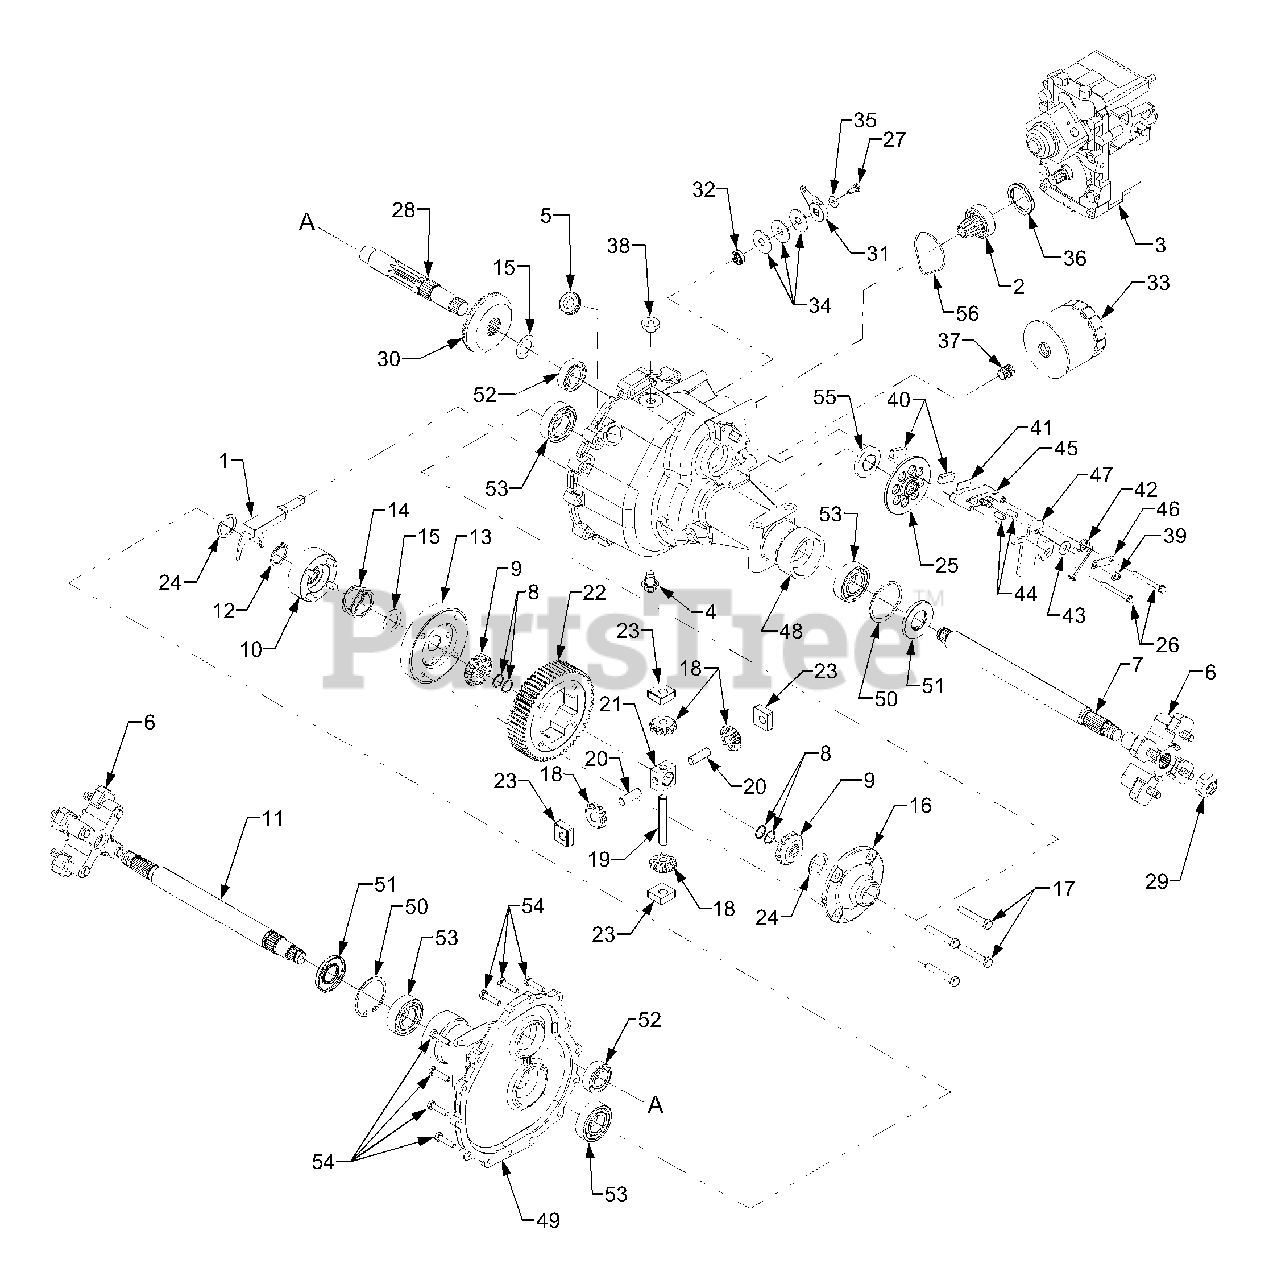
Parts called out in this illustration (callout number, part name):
1	Shaft, Differential Actuator
2	Gear Assembly, Pinion 13T
3	Hydrostatic Transmission Assy.
4	Plug, Drain, M14 x 1.5 x .827
5	Grommet, Rubber
6	Hub Assembly, Wheel
7	Axle Shaft, 15.08 Long - RH
8	Retaining Ring
9	Gear, Spur, 14T
10	Collar Assembly, Diff. Lock
11	Axle Shaft, 15.08 Long - LH
12	Retaining Ring
13	Housing, Diff. Lock
14	Spring, Compression
15	Washer, Thrust, 1.007 x 1.542 x .03
16	Housing, Diff. Cover
17	Hex Cap Screw, 3/8-24 x 2.25 GR8
18	Gear, Differential 10T
19	Shaft, Cross, .5 x 3.485
20	Shaft, Cross, Special
21	Differential Pinion Block
22	Gear, Spur 60T
23	Block, Thrust Miter
24	Washer, Flat, 1.187 x 1.56 x .062
25	Disc, Brake
26	Screw, Hex Wash. Hd. Tapp 1/4-20 x 2.375
27	Hex Cap Screw, 1/4-20 x .62 GR5
28	Shaft, Output 9T
29	Nut, Lock, 7/8-14
30	Gear, Bevel 54T
31	Arm, Diff. Lock Actuator
32	Seal, Oil
33	Filter, Oil
34	Washer, Flat, .51 x 1.5 x .07
35	Washer, Belleville, .265 x .75 x .062
36	Washer, Spring
37	Fitting, Filter Nipple
39	Nut, Hex Insert Lock, 5/16-24
40	Pad, Brake
41	Plate, Puck
42	Spring, Torsion
43	Washer, Flat, .343 x .88 x .062
44	Pin, Brake Actuator
45	Yoke, Brake
46	Bracket, Brake Anti-Rotation
47	Arm, Brake Actuator
48	Housing, RH
49	Housing LH
50	Retaining Ring
51	Seal, Oil
52	Bearing, Ball
53	Bearing, Ball
54	Screw, Hex Cap Locking 5/16-18 x 1.25 GR5
55	Seal, Oil 1.0 ID
56	Seal, Gland O-Ring
